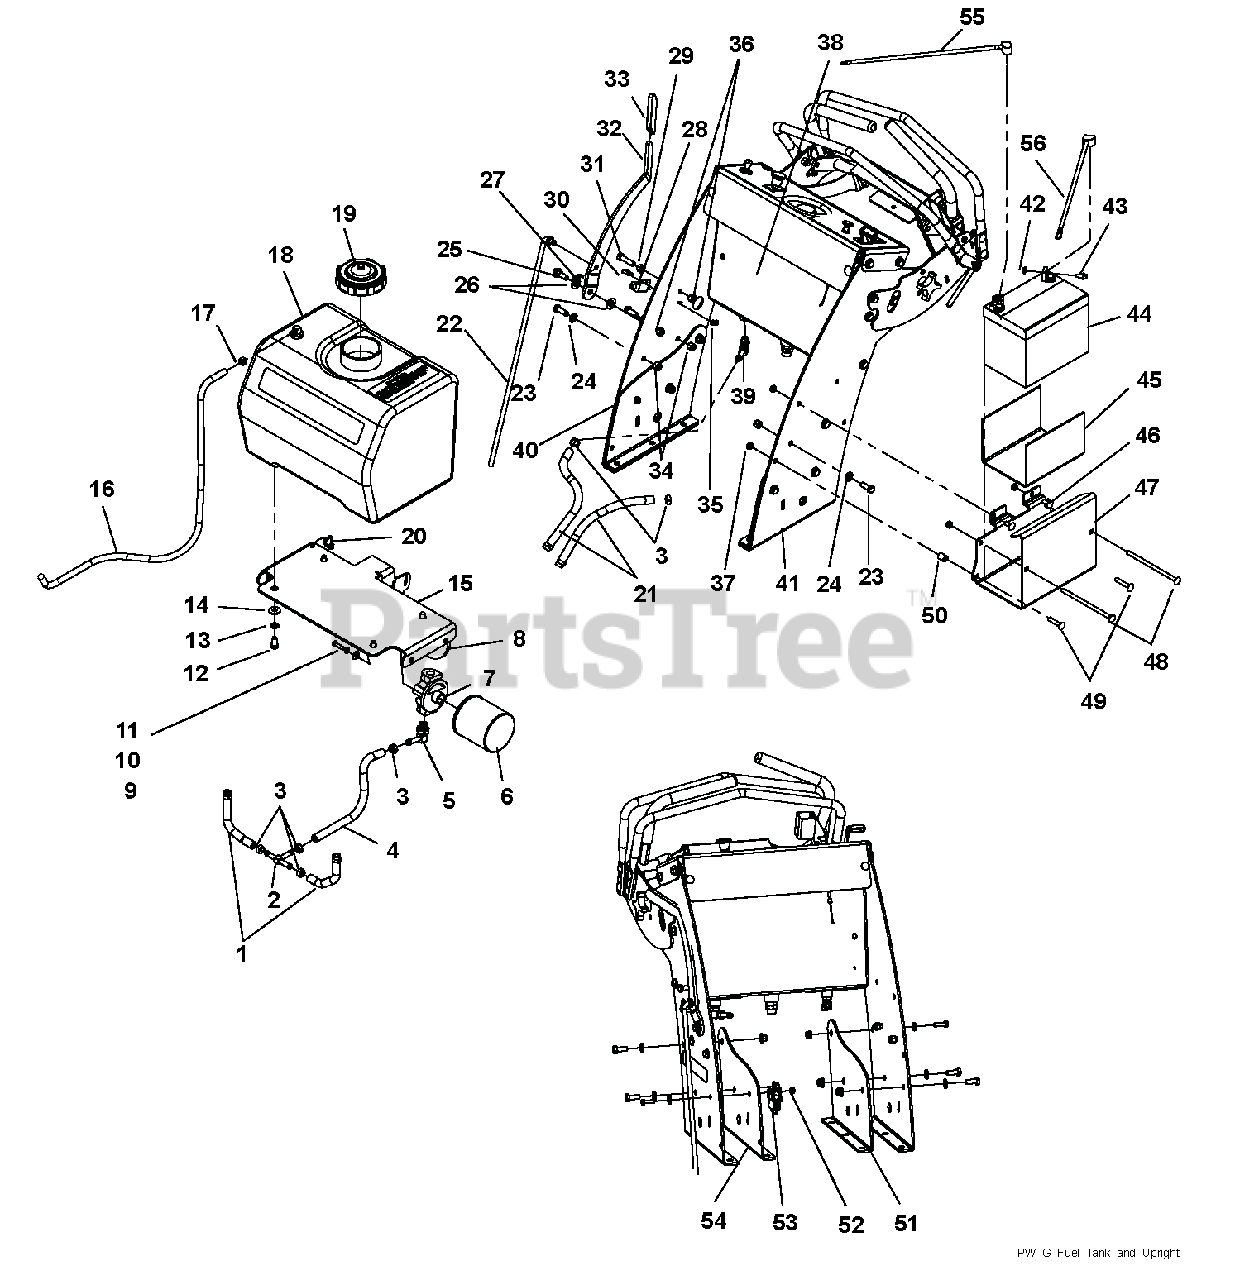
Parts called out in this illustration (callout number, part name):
1	HOSE, HYD 3/8 X 6.00
2	FTG, TUN 3/8 HOSE
3	CLAMP, HOSE - 1/2" PINCH
4	HOSE, HYD .375X10.5
5	FTG, 90 BRB-OR 4601-06-08
6	FILTER, OIL
7	HEAD, OIL FILTER
8	GUARD, HYDRO FILTER FLWLK
9	FLATWASHER 1/4 USS HRD YZ
10	Washer, .250 Medium Spring Lock
11	BLT-HEX .25-20X1.00 GR5 YWZC
12	BLT-HEX .38-16X.75 GR5 YWZC
13	WASHER, .375 MED SPRG LOCK Y
14	WASHER, .375 REG FLAT Y
15	BRACKET, FUEL TANK RMHF
16	HOSE, FUEL 1/4 X 30.00
17	CLAMP, FUEL LINE
18	TANK - FUEL
19	CAP, FUEL S/O
20	CABLE TIE, .15 X 8.50
21	HOSE, HYD .375X11.5
22	ROD, DRIVE CONTROL FW
23	BLT-HEX .38-16X1.00 GR5 YWZC
24	WASHER, .406X.813X.065 FLAT Y
25	BOLT, 1/2X1.06X3/8-16 SLD 5 Y
26	WASHER, .510X1.00X.068 NYLON
27	RING, RUE .375 X .054 X 1.254
28	SWITCH- DOUBLE POLE N.O./N.O.
29	LOCKNUT, 3/8-16 WHIZ Y
30	SCREW, 10-24X.625 PAN PHL MACY
31	BLT-HEX .38-16X1.50 GR5 YWZC
32	LEVER, HAND BRAKE FLOAT WALK
33	GRIP, PVC .250 X 1.00 X 3.63
34	LOCKNUT, 3/8-16 NYLOC Y
35	LOCKNUT, 10-24 NYLOC Y
36	LOCKNUT, 3/8-16 CENTER Y
37	LOCKNUT, 5/16-18 NYLOC Y
38	WLDT, TANK
39	FTG, 90 9/16MOR X 3/8HOSE
40	WLDT, RH UPRIGHT TOWER 36 G2
41	WLDT, LH UPRIGHT TOWER 36 G2
42	LOCKNUT, 1/4-20 WHIZ Y
43	BOLT, 1/4-20X.625 WSH Y
44	BATTERY, 12V-U1-CCA270MIN
45	STRIP, RUBBER
46	BLT-RDHDSQNK .31-18X.75 G5YZ
47	TRAY, BATTERY ELEC HYDRO
48	BOLT, 5/16X6 LONG NK RD HD D-Z
49	BLT-RDHDSQNK .31-18X1.75 G5YZ
50	BUSHING, .364X.540X.700 Y
51	PLATE, DOUBLE LH UPRIGHT BI
52	Locknut, .25-20 Nyloc
53	MODULE, ELECTRONIC
54	PLATE, DOUBLE RH UPRIGHT BI
55	CABLE, BATTERY GROUND 25"
56	CABLE, BATTERY POSITIVE 25"
